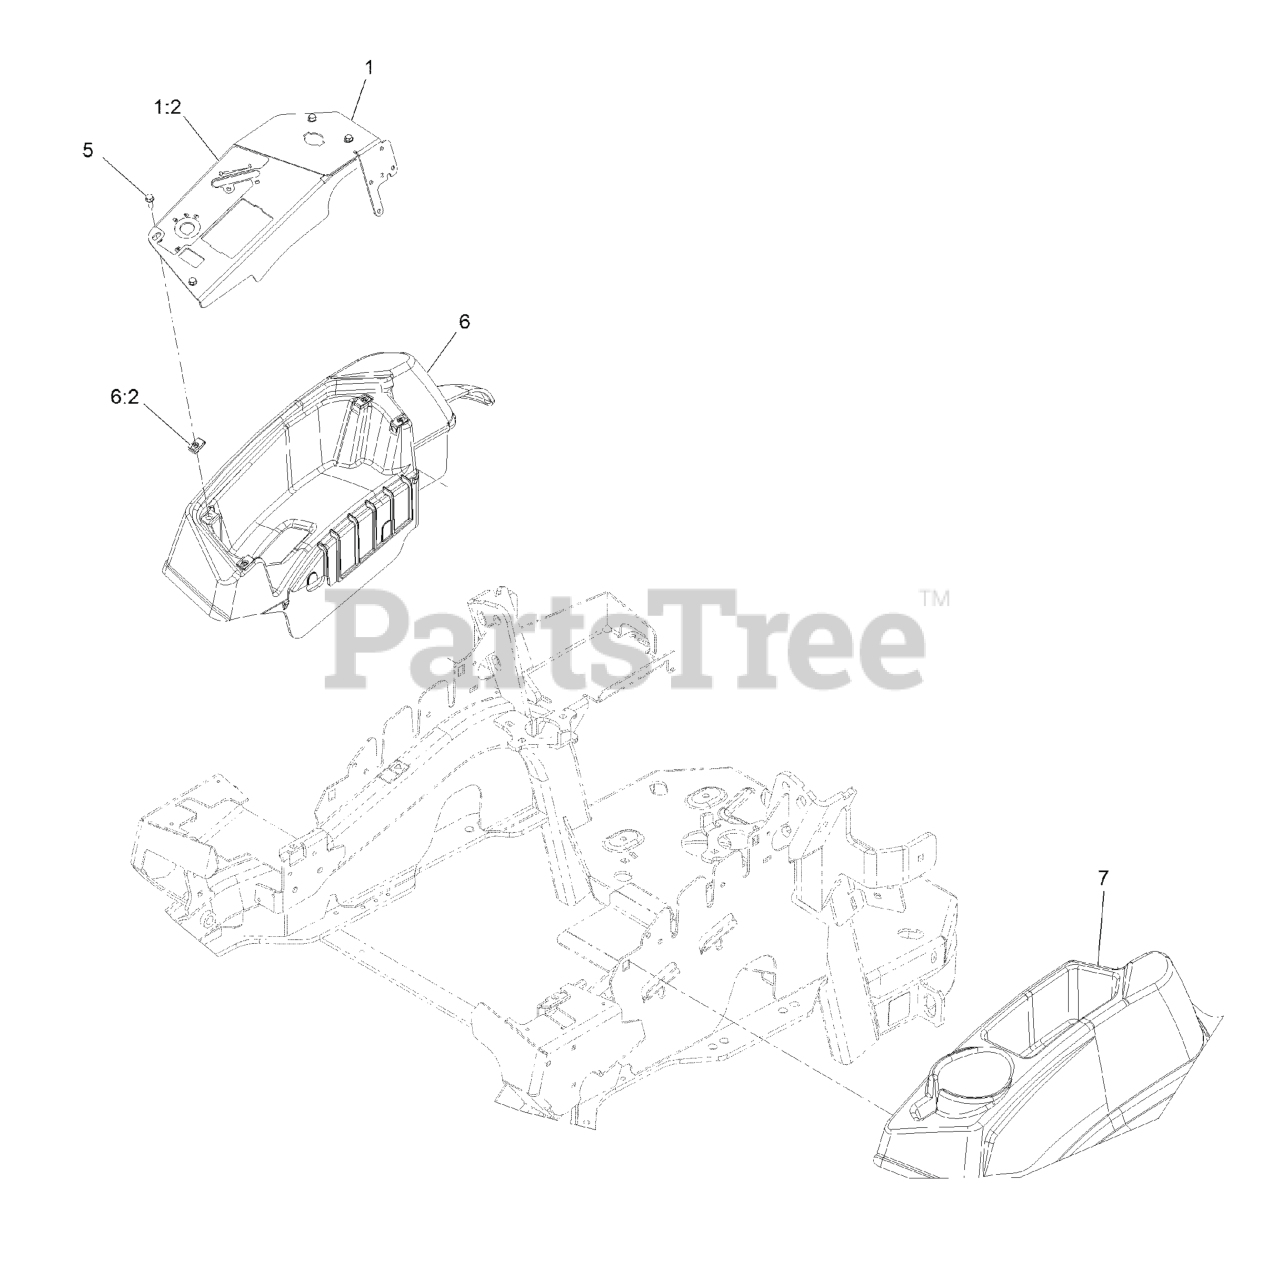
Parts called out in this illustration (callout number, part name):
1	CONSOLE,PANEL W/DECAL
1:2	DECAL-CONTROL PANEL NON-E
1:3	DECAL-FUSES
2	ASM, CHOKE CABLE
3	ASM,THROTTLE CABLE
4	BOLT-CARR
5	NUT-LOCK, NI
6	SCREW-HWH
7	CONSOLE,RH AS ASM
8	CONSOLE, LH AS
9	CLAMP-HOSE
10	PLUG-PLASTIC
